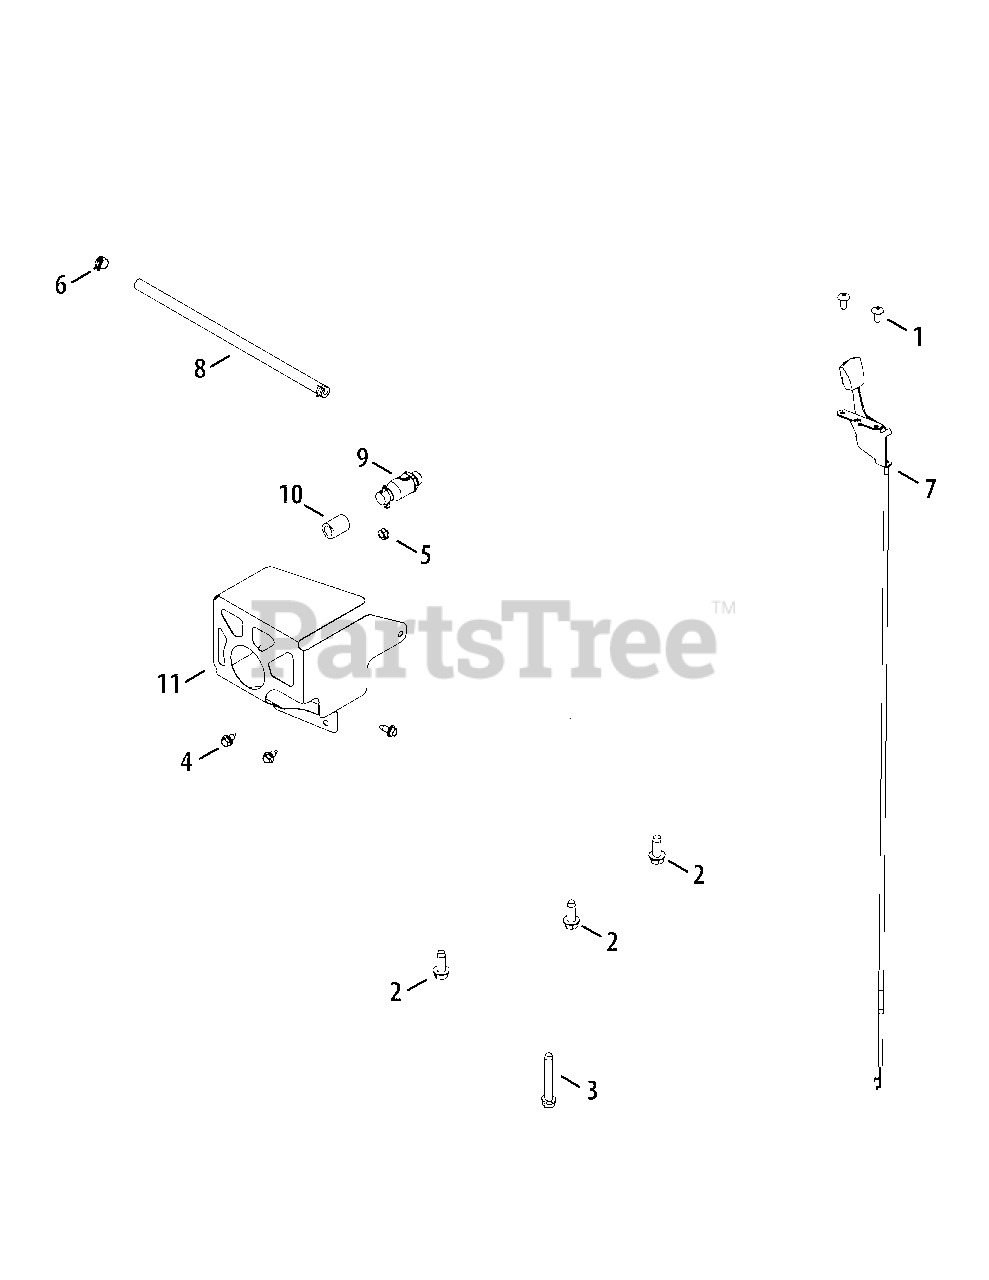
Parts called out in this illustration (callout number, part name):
1	Tap Screw, 1/4-20, 0.500
2	Tap Screw, 3/8-16, 1.000
3	Tap Screw, 3/8-16, 2.250
4	Tap Screw, 1/4-20, 0.625
5	Sems Nut, 1/4-20
6	Hose Clamp, .490 DIA.
7	Throttle/Choke Cable 31 Lg.
8	Low Permeation Fuel Line, 1/4
10	Oil Drain, Extension Hose
11	Muffler Cover
